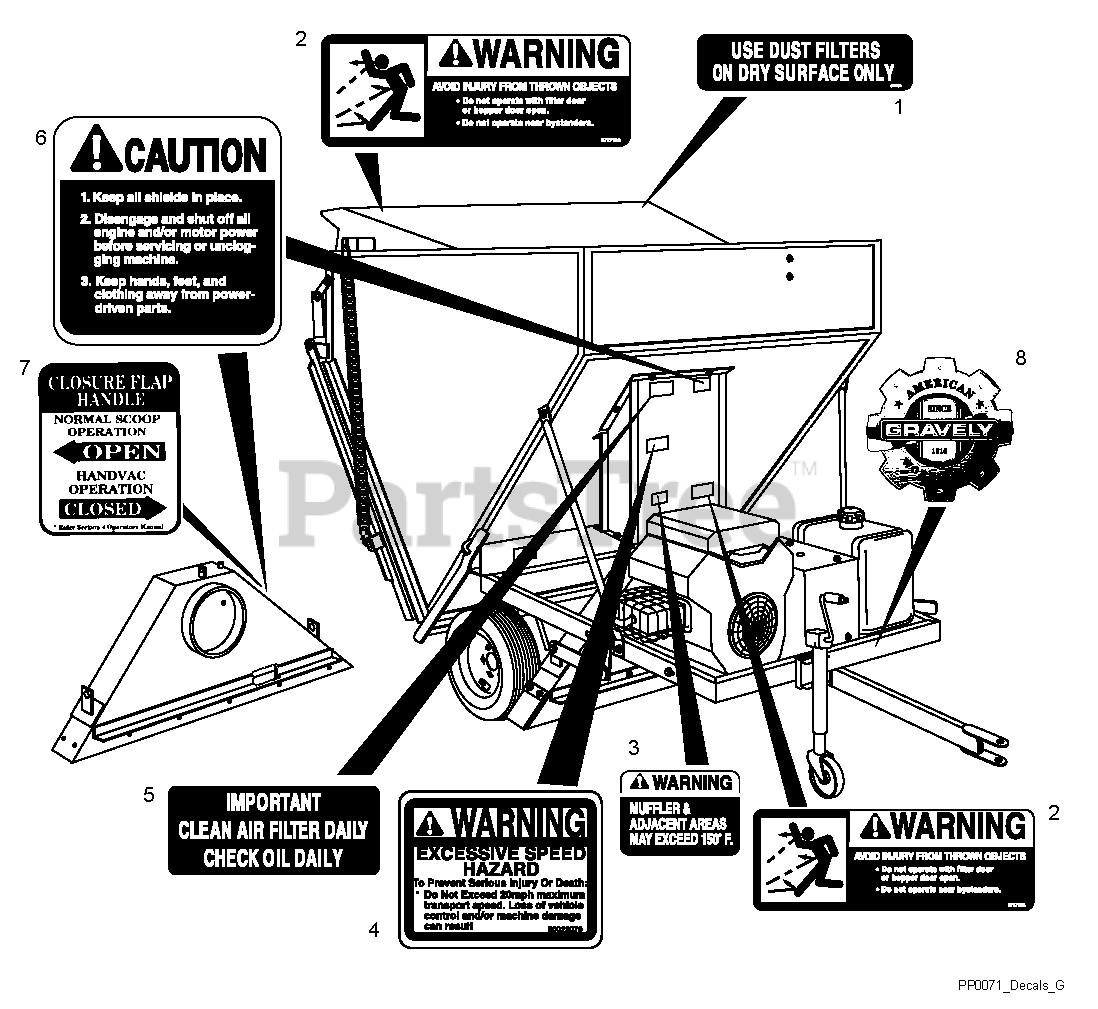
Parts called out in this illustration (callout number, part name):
1	Decal, Dust Filters
2	Decal, Warning Avoid Injury
3	Decal, Warning
4	Decal, Warning
5	Decal, Air Filter
6	Decal, Caution Shields
7	Decal, Closure Flap
8	Decal, Gravely Heritage, Large
